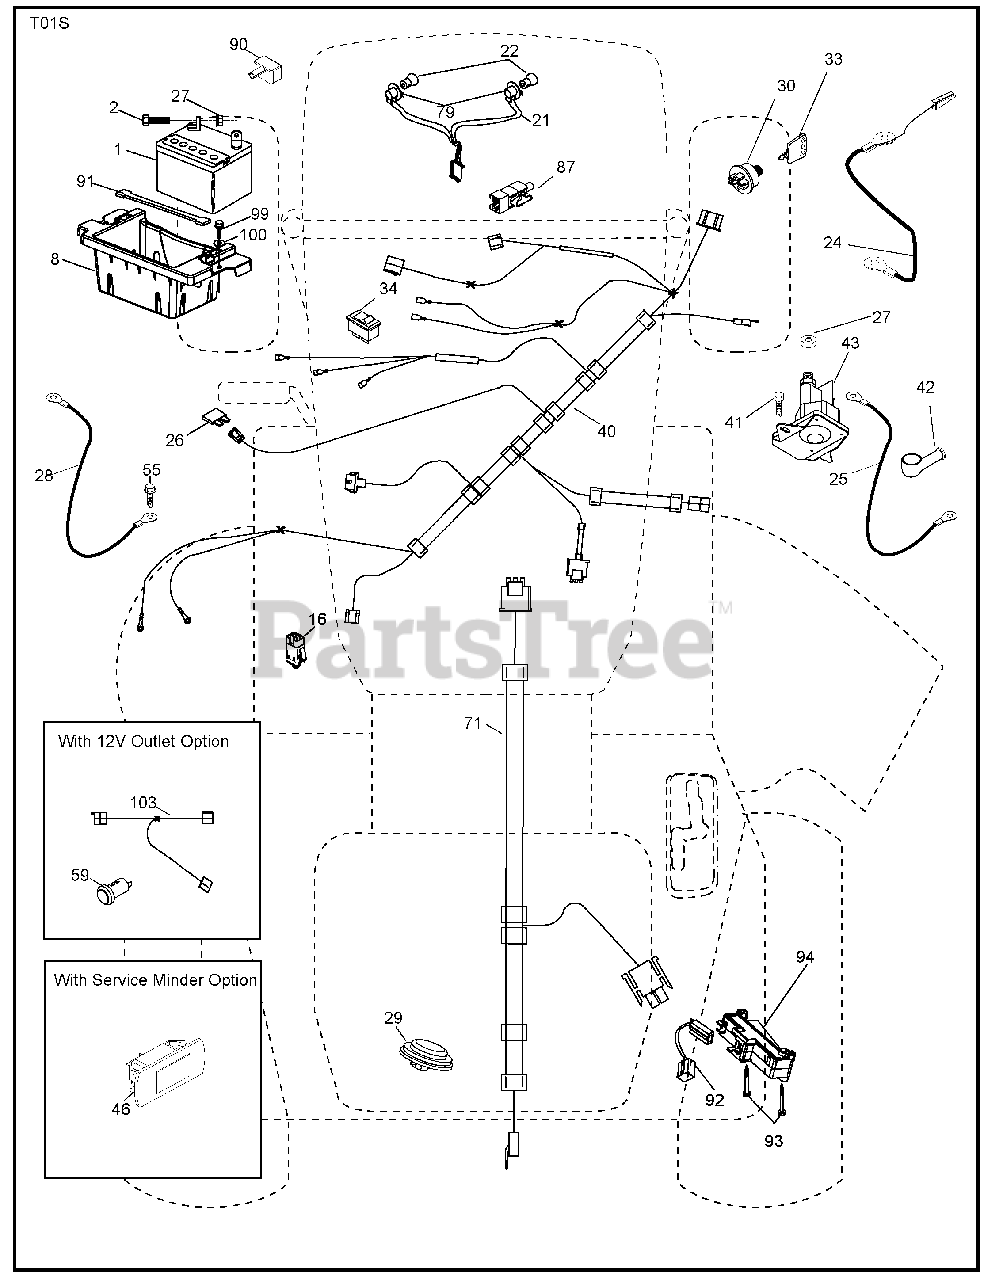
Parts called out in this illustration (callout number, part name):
1	Battery
2	Bolt Hex Head 1/4-20 x 3/4
8	Box Battery
16	Switch Interlock Push-In
21	Harness Socket Light w/4152J
22	Bulb Light
24	Cable Battery
25	Cable Starter
27	Nut Keps Hex 1/4-20 unc
28	Cable, Ground
29	Switch, Seat
30	Switch, Ign
34	Switch Light/Reset
40	Harness Ign. Dash
41	Screw Thd Cut 1/4-20 x 1/2
42	Cover, Terminal
43	Solenoid
55	Screw Thdrol 5/16-18 x 3/4
71	Harness Chassis
79	Socket Asm Bulb Twistlock
87	Switch Interlock Clutch Cable
90	Cover, Terminal Battery
91	Strap Battery Mount Front
92	Harness Pigtail Reverse Switch
93	Screw Plastite 10-14 x 2.0
94	Module Reverse ROS
99	Screw Hexwsh Thdrol 1/4-20 x 3/4
100	Washer 9/32 x 7/8 x 16 Ga.
